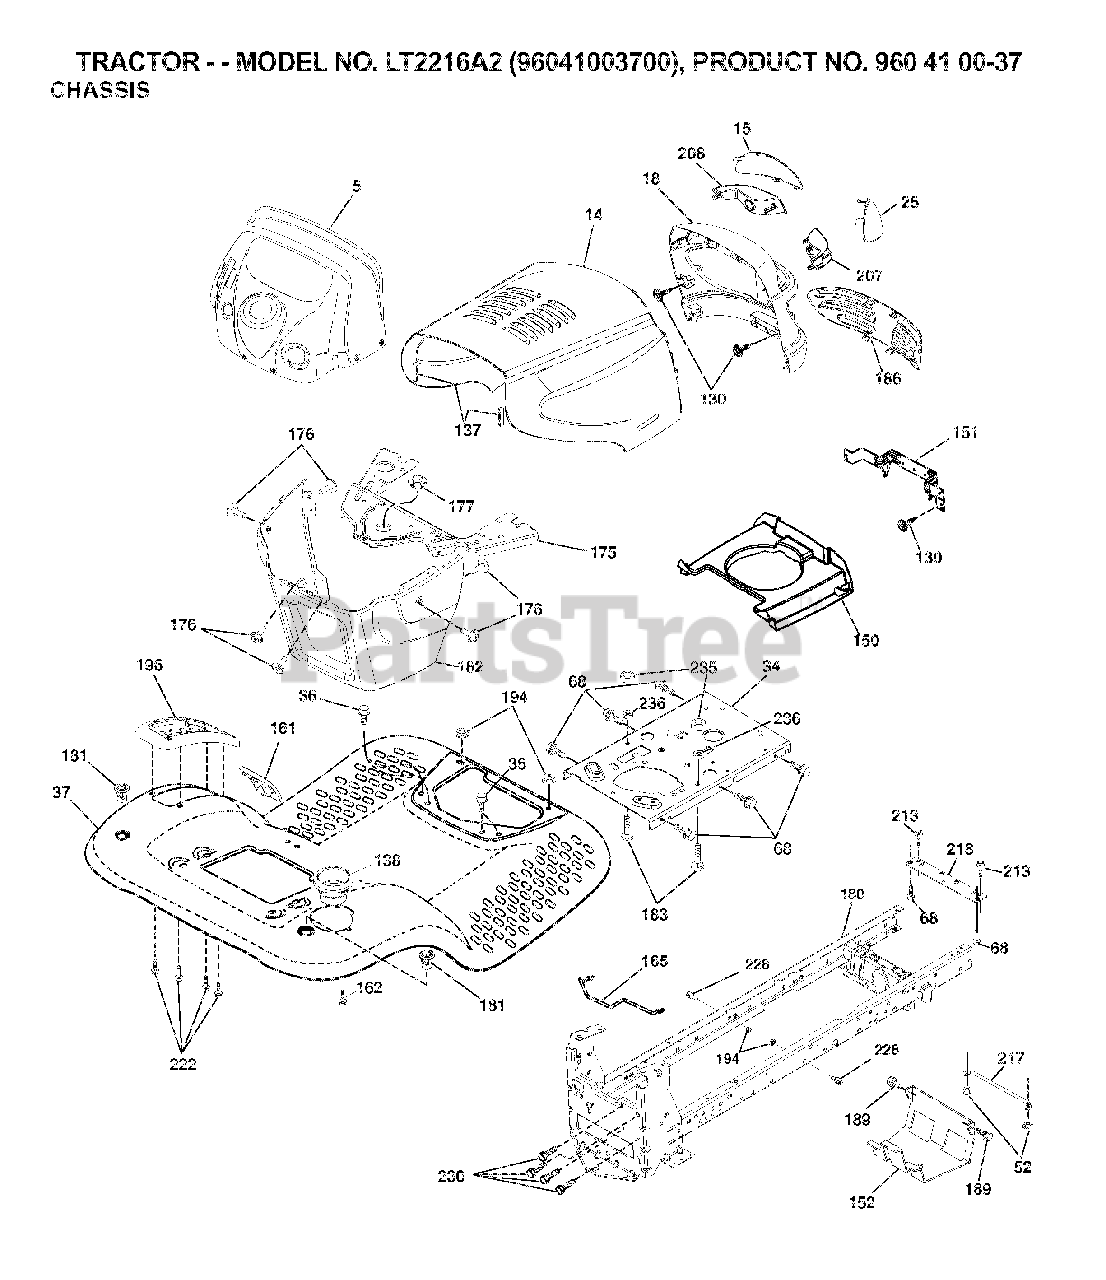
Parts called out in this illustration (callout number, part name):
34	PLATE.ENGINE.WELDED.CHASSIS
36	SCREW 5/16"
52	LOCKNUT
130	SCREW
137	BUMPER.HOOD.LARGE.1.75"
138	CUPHOLDER.TL.TEX.BLACK
151	BRACKET PIVOT
152	SHIELD BROWNING
161	WINDOW.FUEL.LT.TEX.BLACK
162	SCREW.HI-LO.CONSOLE
165	SUPPORT.TANK.REAR.W/TE
175	CROSSMEMBER.LT
176	SCREW.#10-24X5/8.RN.QU
177	BUSHING STEERING
180	CHASSIS
181	FEND/FTRST.PCH.CPH.NFW
182	DASH.LOWER.LT.CCS
183	BOLT.5/16-18X1-1/4 FULL.THREAD
189	SCREW
194	NUT LOCK HEX FLANGE 5/16-18
196	CONSOLE.ASM.DECK.LIFT.TLT.BLAC
207	BEZEL GRILL RH
208	BEZEL GRILL LH
213	BOLT
217	ROD PIVOT CHASSIS/HOOD
218	X-PIECE.HOOD.STOP.NON/
222	SCREW.1/4-20X5/8
228	STUD.FASTNER.W/ANTI-ROTATE
230	SHOULDER BOLT 5/16-18TT
235	SPACER FENDER
236	NUT.CENTERLOCK.5/16-
